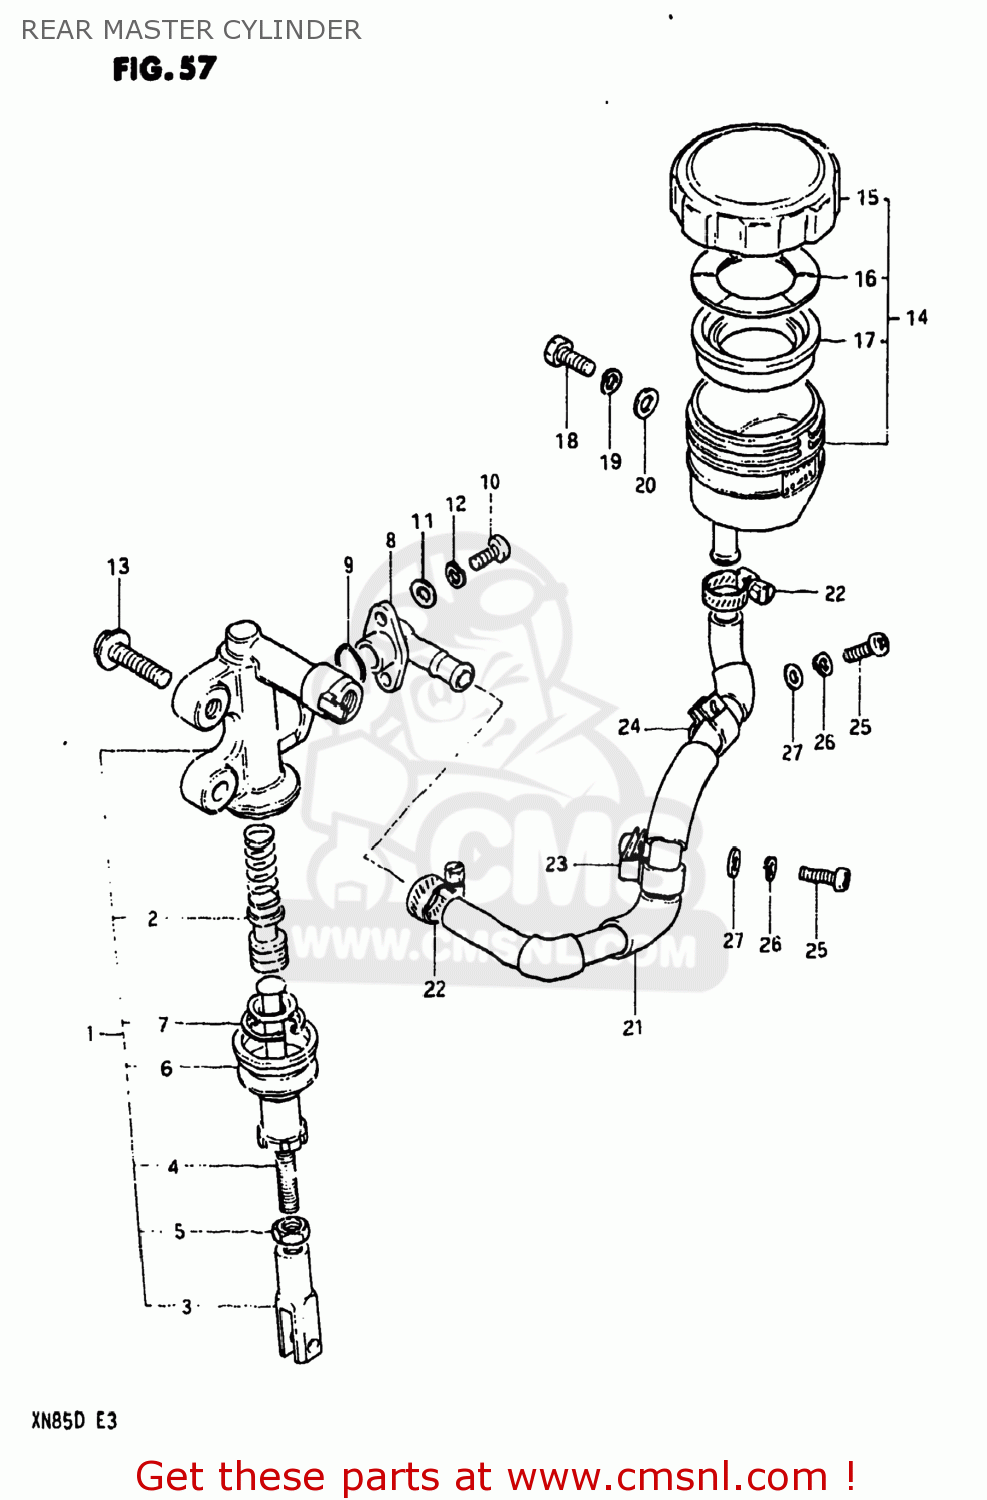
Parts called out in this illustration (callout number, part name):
1	CYLINDER ASSEMBLY,REAR MASTER
2	PISTON/CUP SET
3	YOKE
4	ROD,PUSH
5	NUT,MASTER CYLINDER
6	BOOT
7	CIRCLIP
8	CONNECTOR,HOSE
9	O RING
10	SCREW
11	WASHER
12	LOCK WASHER
13	BOLT
14	TANK ASSEMBLY,RESERVOIR
15	CAP
16	PLATE,DIAPHRAGM
17	DIAPHRAGM
18	BOLT L:16
19	LOCK WASHER
20	WASHER
21	HOSE,RESERVOIR TANK
22	CLAMP
23	CLAMP
24	CLAMP
25	SCREW 6X12
26	LOCK WASHER
27	WASHER
